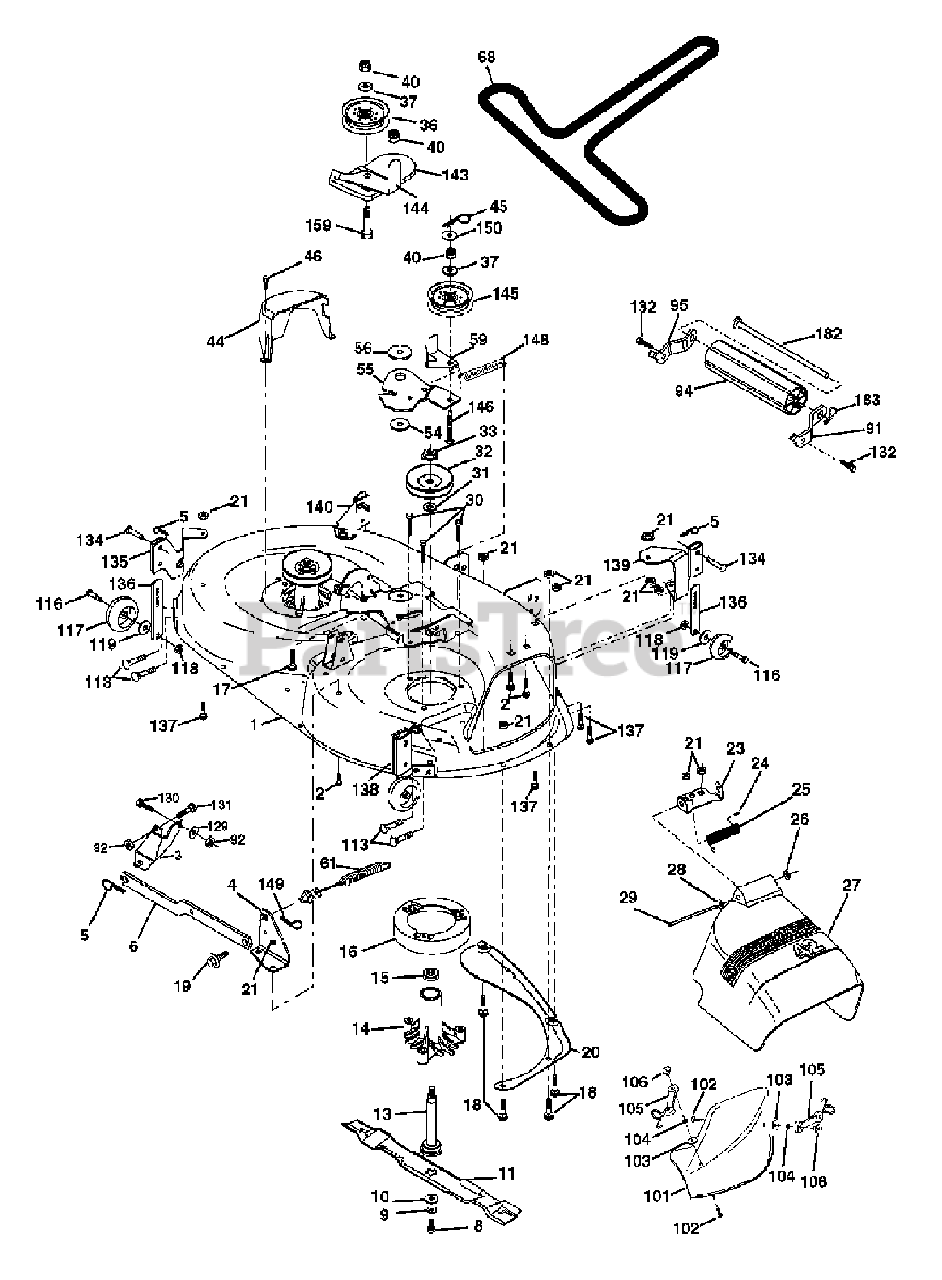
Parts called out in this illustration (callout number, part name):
1	Mower Deck Assembly, 42"
2	Bolt
3	Bracket Assembly,Sway Bar, Front
4	Bracket Sway Bar 42" Deck
5	Retainer Spring
6	Bar Sway Deck
8	Bolt, Hex 3/8-24 x 1.25 Gr. 8
9	Washer, Lock
10	Washer, Hardened
11	Blade Mower 42 High Perf.
11	Blade, Mulching
13	Shaft Assembly, Mandrel, Vented
14	Housing, Mandrel, Vented
15	Bearing, Ball, Mandrel
17	Bolt Rd Hd 3/8-16 Unc x 1-3/4 Gr. 5
18	Bolt, Carriage 5/16-18 x 5/8
19	Bolt, Shoulder
20	Baffle, Vortex
21	Nut Crownlock 5/16-18 UNC
23	Bracket, Deflector
24	Cap, Sleeve
25	Spring, Torsion, Deflector
27	Shield, Deflector
28	Washer 11/32 x 5/8 x 16 Ga.
29	Rod, Hinge
30	Screw Thdrol Hex
31	Washer, Spacer
32	Pulley, Mandrel
33	Nut, Toplock, Flanged
36	Pulley, Idler, Flat
37	Washer 13/32 x 13/16 x 16 Ga.
40	Nut Crownlock 3/8-16 UNC
44	Guard, Mandrel, L.H.
45	Retainer
46	Screw, Thd. Roll 1/4-20 x 5/8
54	Washer, Hardened
55	Arm, Idler
56	Spacer, Retainer
59	Guard, TUV Idler
61	Spring Ext Elect Clutch 42" Dck
91	Bracket Asm Noseroller Lh
92	Nut Lock Hex w/Ins. 3/8
94	Roller Nose 38-50
95	Bracket Asm Noseroller Rh
101	Mulcher Cover
102	Screw
103	Washer #10
104	Washer, Lock
105	Latch Assembly, Bagger
106	Nut, Weld
113	Screw 5/16-18 x 3/4 Tap R
116	Bolt, Shoulder
117	Wheel, Gauge
118	Nut, Centerlock 3/8-16
119	Washer 3/8 x 7/8 x 14 Gauge
129	Washer 13/32 x 13/16 x Ga.
130	Bolt Fin Hex 3/8-16unc x 1 Gr.5
131	Bolt Rdhd Sqnk 3/8-16unc x 1
132	Screw 3/8-16 x .75
134	Pin Head Rivet
135	Bracket Asm Whl GA R LH
136	Bar Adjusting GA WHL
137	Bolt Carr 5/16-18 x 5/8
138	Bracket Asm Whl GA R RH
139	Bracket Asm Whl GA F RH
140	Bracket Asm Whl GA F LH
143	Bracket Arm Idler 42"
144	Keeper Belt 42" Clutch Cable
145	Pulley Idler Flat
146	Bolt Carriage Idler
148	Spring Return Idler
149	Retainer Spring Yellow Zinc
150	Washer 9/32 x 3/4 x 16 Ga.
159	Bolt Rdhd Sqn 3/8-16 UNC x 1- 3/4
182	Rod Roller Nose
183	Retainer Spring
